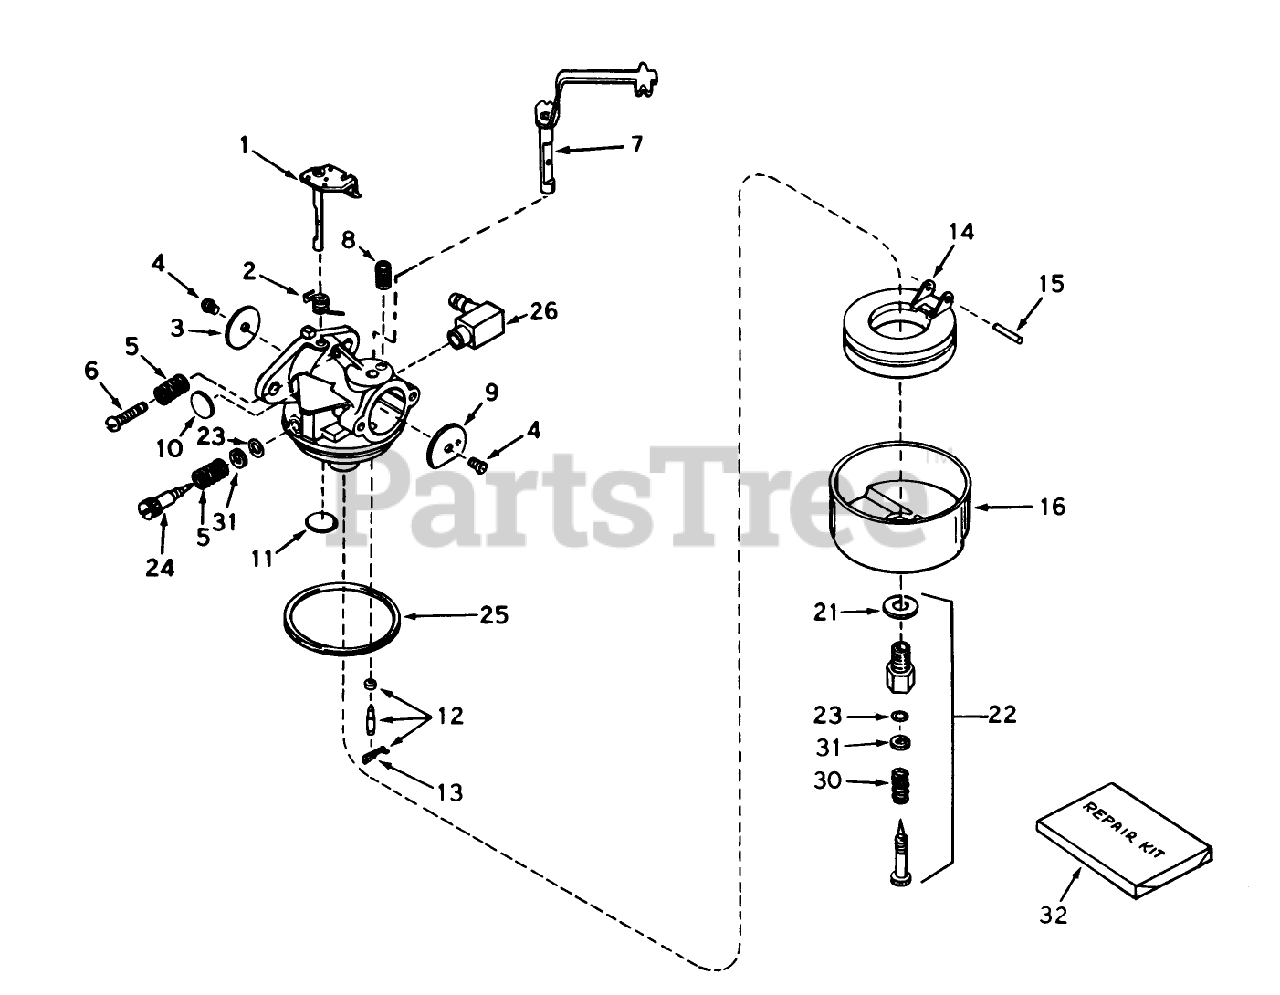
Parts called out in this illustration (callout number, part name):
1	Throttle Shaft and Lever ASM
2	Spring, Throtte Return
3	Shutter-Throttle
4	Screw-Shutter
5	Spring-Tension
6	Screw-Throttle Crack Screw / Idle Speed
7	Shaft Lever Assy., Choke
8	Spring-Positioning, Choke
10	Plug-Welch, Idle Mixture Well
11	Plug-Welch, Atmospheric Vent
12	Inlet Needle, Seat Clip Assy. (Incl. No. 13)
13	Clip-Spring
14	Float,Carburetor
15	Shaft-Float
16	Bowl-Float (no drain)
21	Washer-Bowl Nut
22	Adjustment Screw Assy., Main (Incl. Nos. 5A, 21 23)
23	ORing
24	Screw, Idle Adj.
25	O Ring-Bowl, Float
26	Fitting-Fuel
30	Spring
31	Washer
32	Repair Kit (Incl. items marked *)
